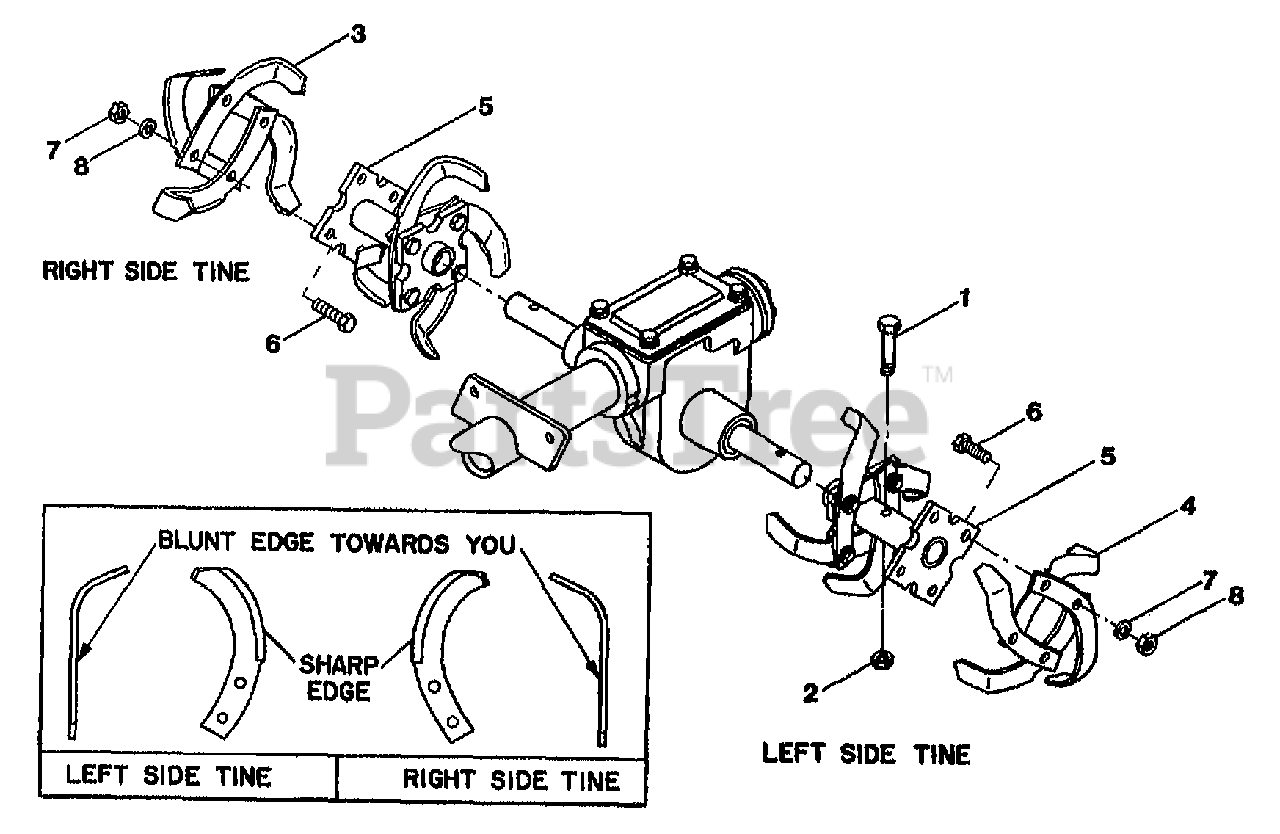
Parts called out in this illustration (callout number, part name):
1	BOLT-HH 3/8-16X1.75 G8 ZP
2	NUT-H/LK 3/8-16
3	TINE-BOLO RIGHT
4	TINE-BOLO LEFT
5	TINE HOLDER-WELD
6	SCR-HH 3/8-16X1.0 G5 ZP
7	WASHER-LK .375 @ DEPL
8	NUT-HEX 3/8-16 ZP
